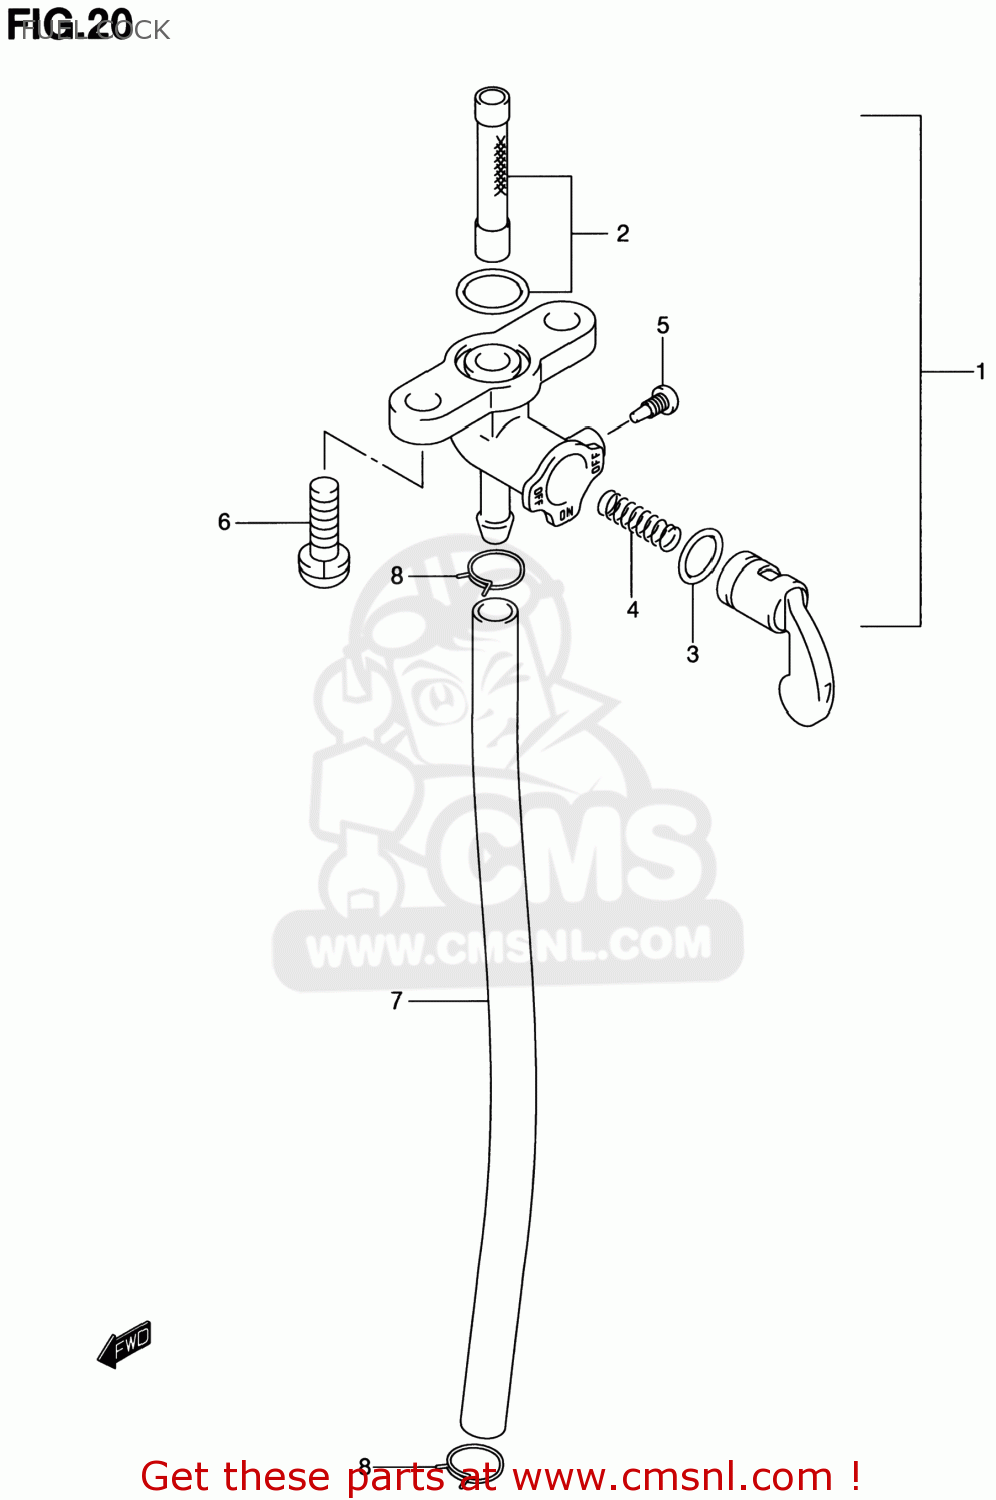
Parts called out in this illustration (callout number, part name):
1	COCK ASSY,FUEL
2	FILTER SET FUEL
3	O RING,LEVER
4	SPRING
5	SCREW
6	SCREW
7	HOSE(5X8.2X600)
8	CLIP
